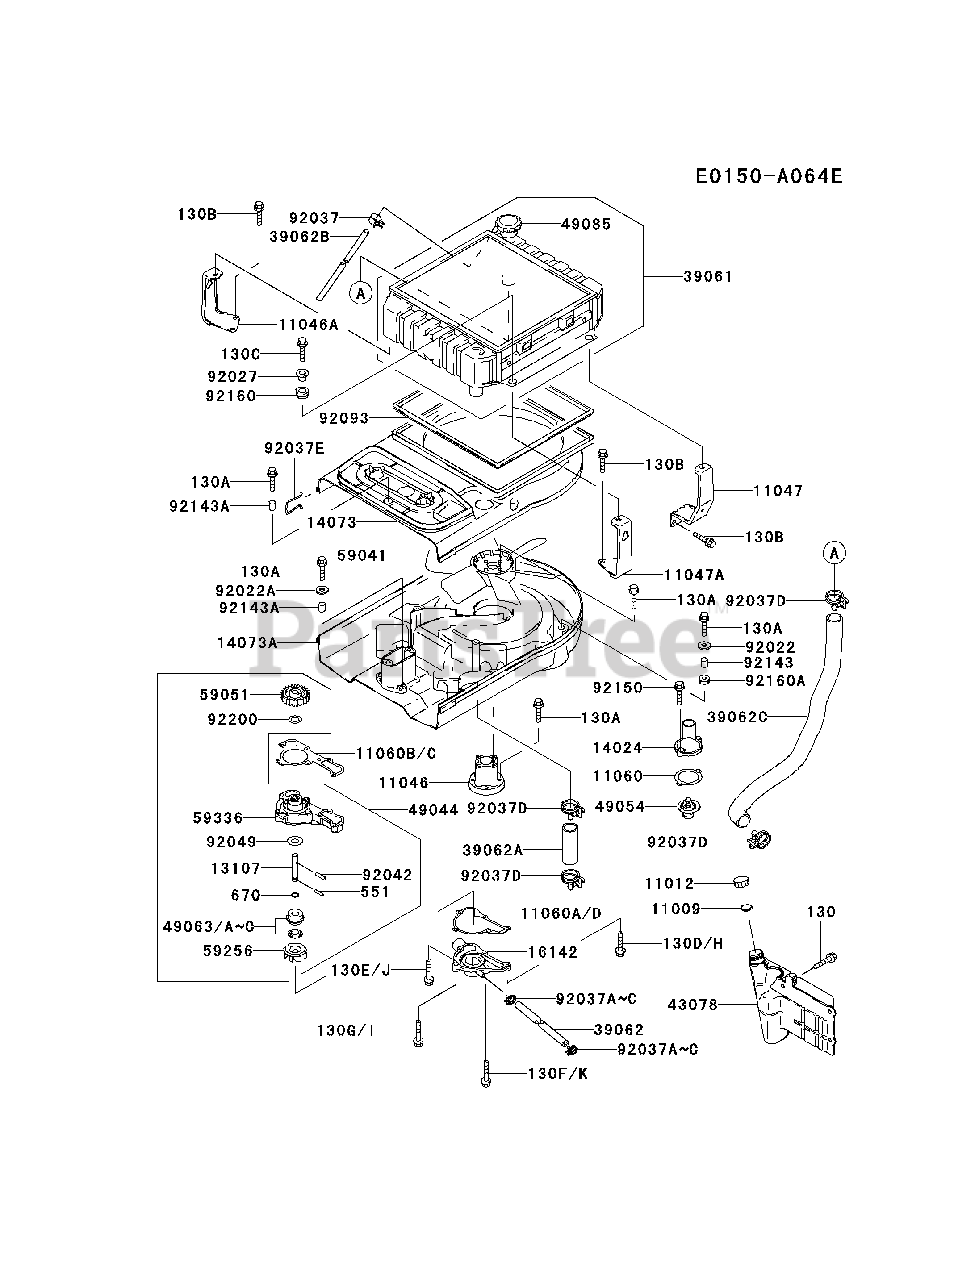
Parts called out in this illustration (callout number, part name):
130	BOLT-FLANGED
130A	BOLT-FLANGED
130B	BOLT-FLANGED
130C	BOLT-FLANGED
130D	BOLT-FLANGED
130E	BOLT-FLANGED
130F	BOLT-FLANGED
130G	BOLT-FLANGED
551	PIN-DOWEL
670	O RING
92150	BOLT,6X20
